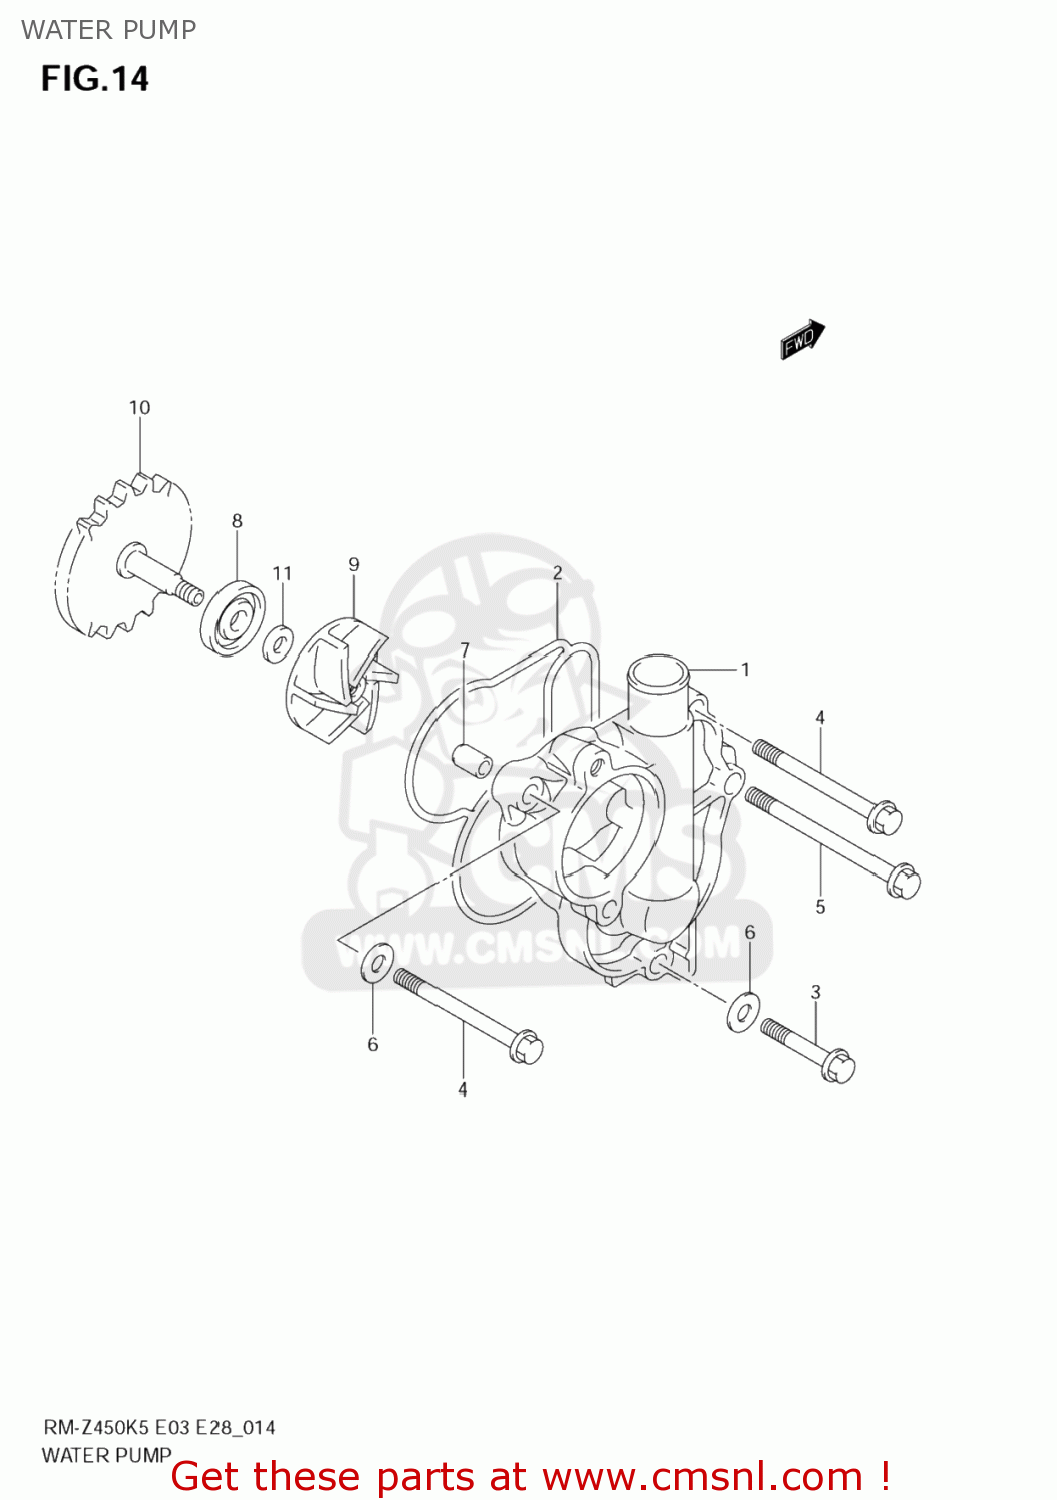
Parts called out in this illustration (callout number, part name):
1	CASE,WATER PUMP & OIL FILTER
2	O RING,WATER PUMP CASE
3	BOLT(6X30)
4	BOLT(6X60)
5	BOLT(6X70)
6	GASKET(6.2X13X1.2) (NAS)
7	PIN(6.2X8X11)
8	SEAL,WATER PUMP OIL
9	IMPELLER,WATER PUMP
10	SHAFT COMP,WAT
11	SHIM(6X14X1)
